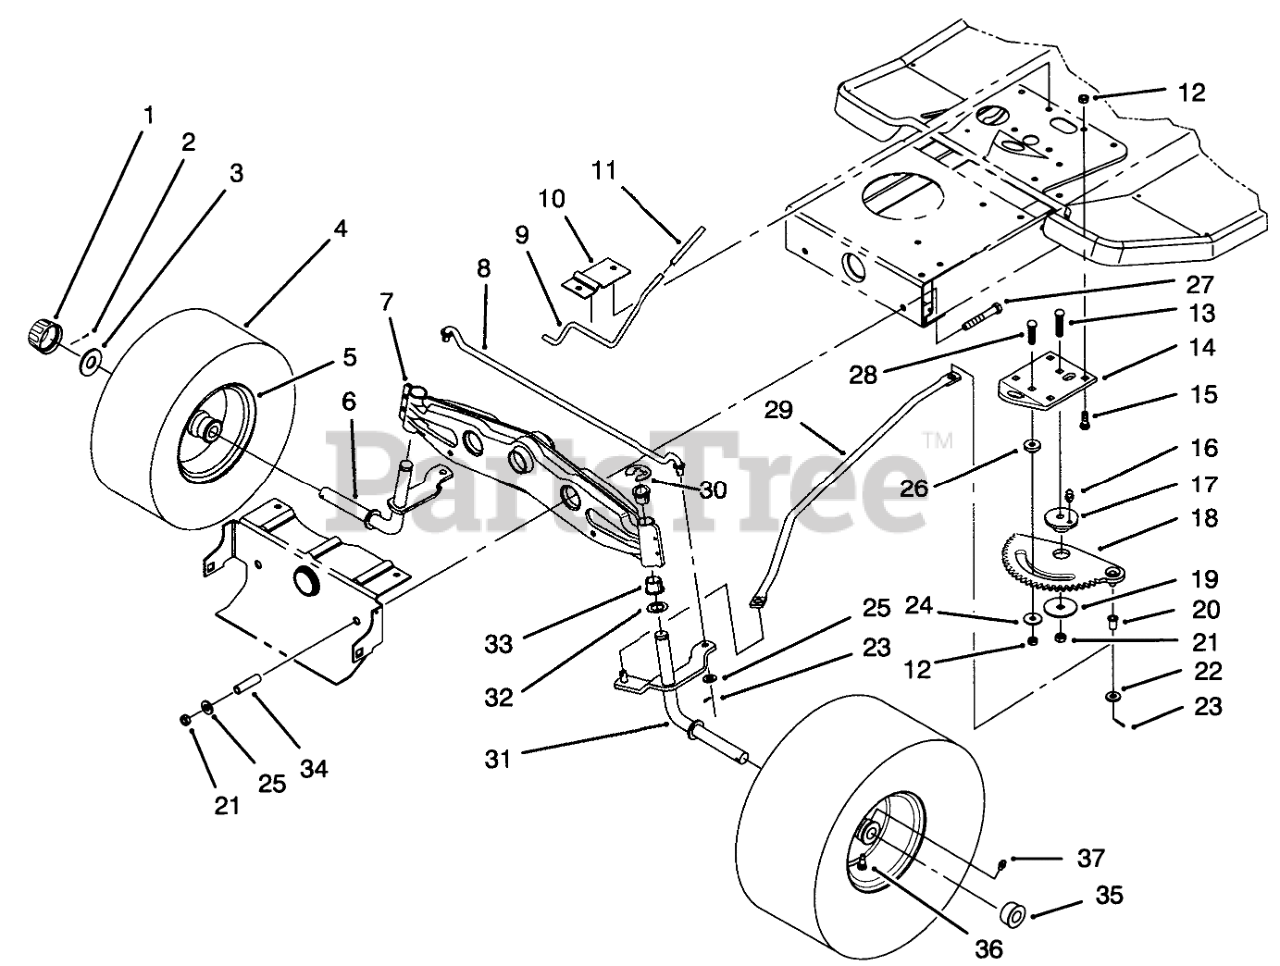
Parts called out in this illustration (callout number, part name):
1	CAP-HUB
2	PIN-COTTER
3	WASHER-PLAIN
4	TIRE 15 X 6.00 X 6
5	RIM ASM
6	Spindle-R.H.
7	Axle-Front
8	TIE ROD-STEERING
9	ROD-BRAKE, PARKING
10	Bracket-Parking Brake
11	GRIP-BRAKE, PARKING
12	NUT-LOCK, NI
13	SCREW-CARR
14	Bracket-Steering Rack
15	BOLT-CARR
16	FITTING-GREASE
17	BUSHING-ECCENTRIC
18	RACK-STEERING
19	WASHER-BEARING
20	BUSHING-FLANGED, NYLON
21	NUT-LOCK, NI
22	WASHER-FLAT
23	PIN-COTTER
24	WASHER-PIVOT
25	WASHER-FLAT
26	SPACER-RACK, STEERING
27	SCREW-HH
28	SCREW-CARR
29	LINK-DRAG
30	E-RING
31	Spindle-L.H.
32	WASHER-THRUST
33	BUSHING
34	SPACER
35	BEARING-WHEEL
36	STEM-VALVE
37	FITTING-GREASE
